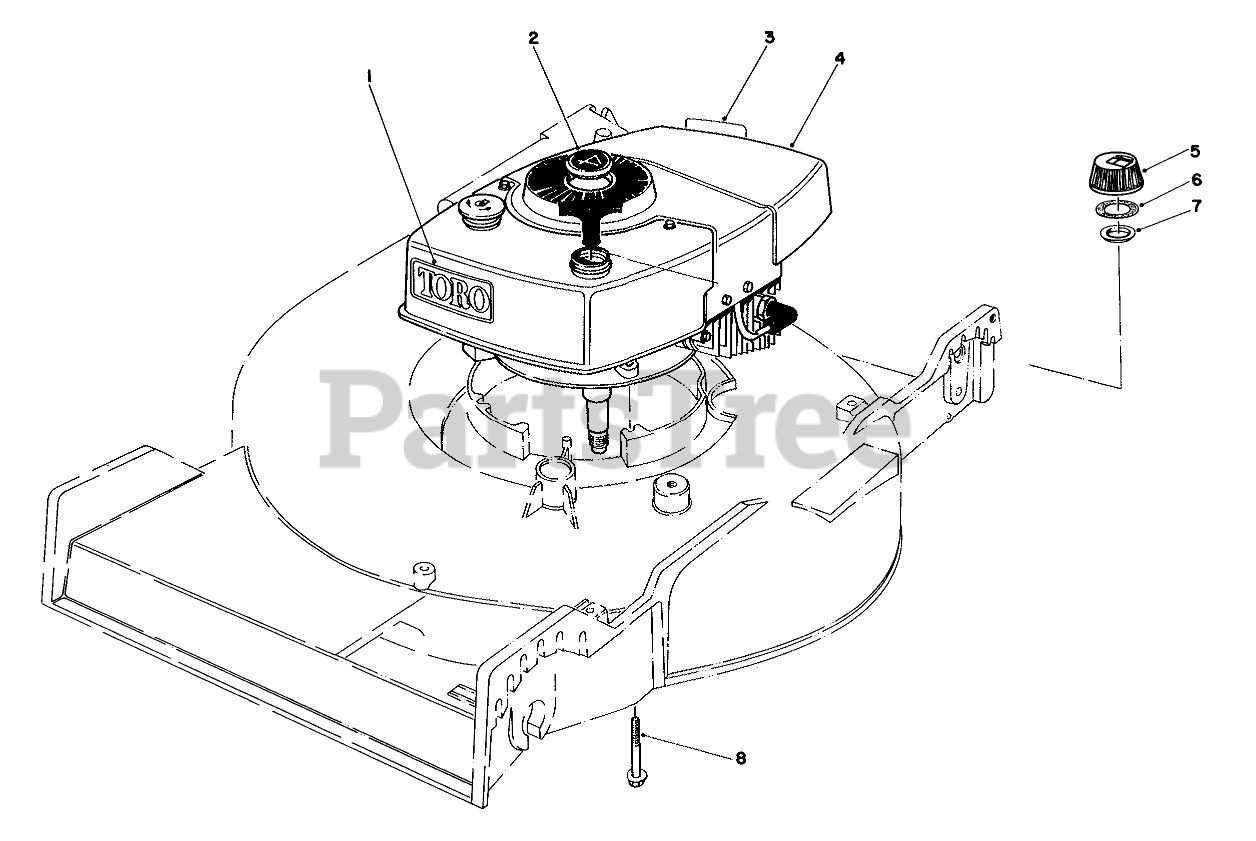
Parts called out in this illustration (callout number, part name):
1	Decal Tow
2	PLUG BUTTON
3	Decal-Maintenan
4	Engine
5	Gas Cap Assembly (Incl. Ref. #6 & 7)
6	GASKET
7	GAS CAP BAFFLE
8	3/8-16 X 2 CAPSCREW
